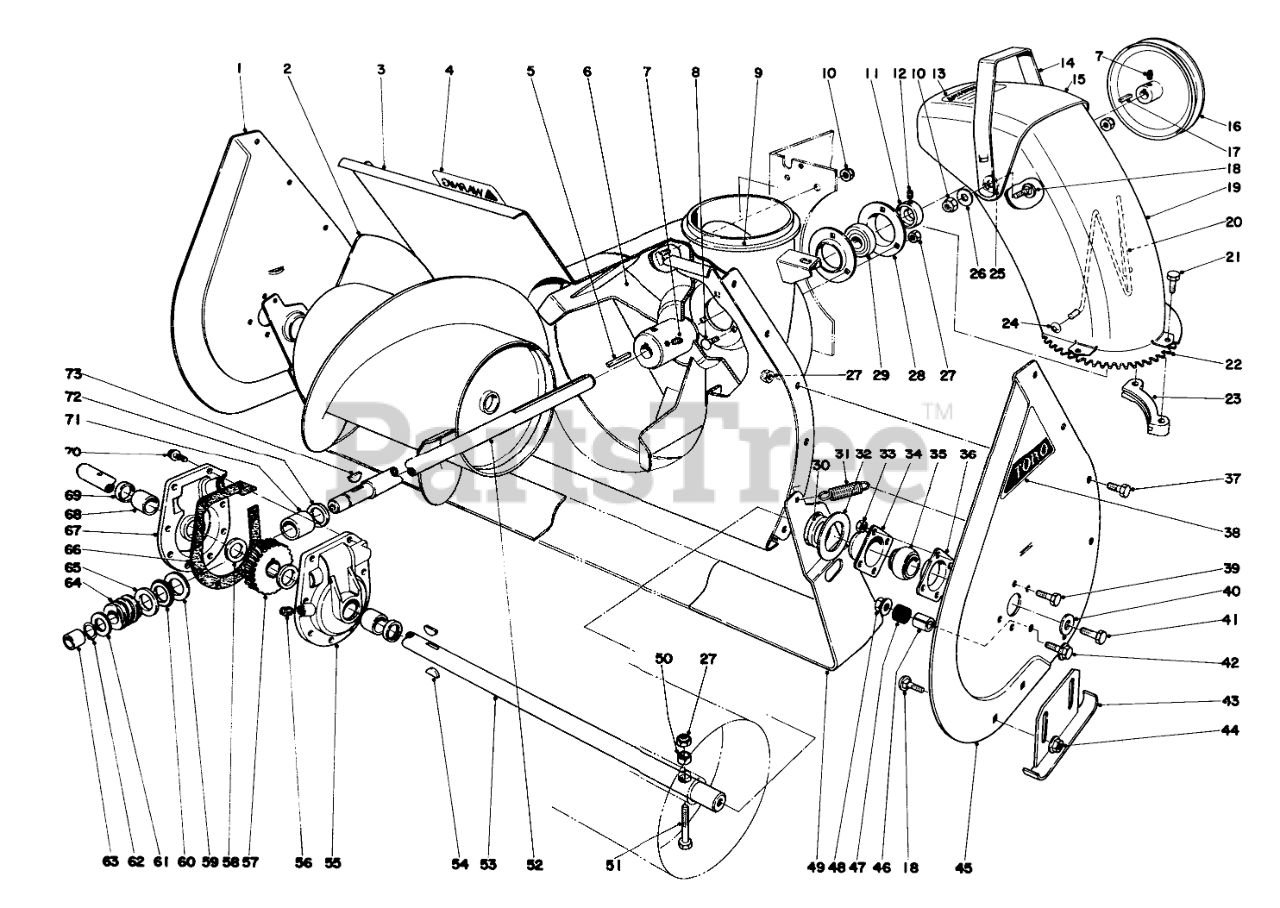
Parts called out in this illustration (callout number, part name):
1	Side Plate Right
2	Auger Right
3	Auger Housing
4	Decal
6	IMPELLER WA RO
7	SCREW-SET, SQH
8	BOLT-CARR
9	SUPPORT B
10	NUT-LOCK, CONE
11	EXT LOCKING COLLAR
12	SCREW-HSH
13	CHUTE WARNING DECAL
14	DEFLECTOR HANDLE B
15	Chute Deflector
16	IMPELLER PULLEY
17	SQUARE KEY
18	SCREW-CARR
19	Chute
20	WIRE-CHUTE
21	Screw
22	Chute Swivel Gear
23	CHUTE RETAINER
24	NUT-PUSH
25	WASHER-RUBBER
26	WASHER-BELLEVILLE
27	NUT-LOCK, CONE
28	BRG FLANGE
29	BALL BRG W/COLLAR
30	WASHER-THRUST
31	SPRING-TENSION
32	SCRAPER BLADE SPACER
33	NUT-LOCK, CONE
34	BEARING-FLANGE, FRONT
35	BEARING
36	BEARING-FLANGE, REAR
37	SCREW-HH
38	AUGER SIDE PLT DECAL
39	SCREW-HH
40	WASHER
41	SCREW-HH
42	SCREW-HHF
43	Skid
44	NUT-HHF, WHIZ
45	Sideplate Auger Left
46	SCRAPER STOP SPACER
47	SCRAPER STOP CUSHION
48	NUT-HF
49	24 SCRAPER BLD
50	SPACER-HUB, AUGER
51	Auger Bolt
52	Impeller Shaft
53	24 AUGER SHAFT
54	KEY-WOODRUFF
55	Gear Case Left Half(Incl. Ref. #68-69)
56	PLUG-PIPE, SQH
57	GEAR-WORM, 27T
58	WASHER-THRUST
59	WASHER-THRUST
60	BEARING-THRUST
61	WASHER-THRUST
62	Ring-Snap
63	BUSHING
65	THRUST-WASHER
66	Gasket
67	Gear Case Right Half(Incl. Ref. #68-69)
68	BUSHING
69	SEAL-OIL
70	SCREW-HWHTF
71	BUSHING-SPECIAL
72	RING-QUAD
73	KEY-WOODRUFF
